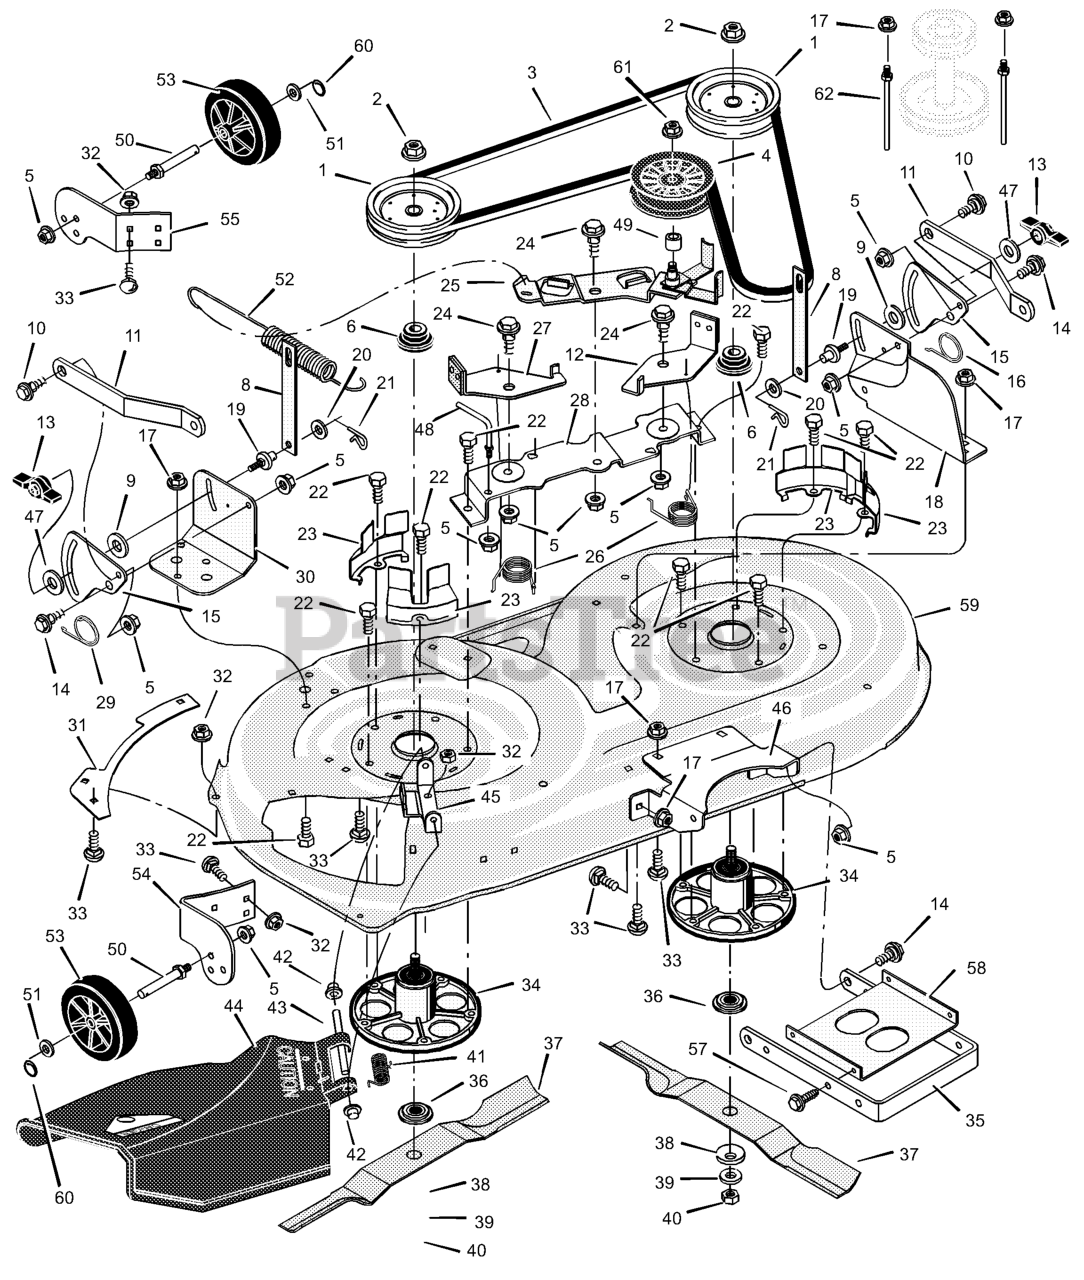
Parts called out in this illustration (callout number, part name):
1	Pulley, Jackshaft
2	Nut, Hex
3	Belt, Mower Drive
4	Pulley, Idler
5	Nut, Flange
6	Spacer, Pulley
8	Link, Lift
9	Pad, Friction
10	Bolt, Shoulder
11	Bracket, Suspension
12	Pad Assembly, Left Brake
13	Knob
14	Bolt, Shoulder
15	Plate, Suspension
17	Nut, Flange
18	Bracket, Suspension
19	Pin, Hanger
21	Pin, Hair
22	Bolt
23	Cover, Pulley
24	Bolt, Shoulder
25	Arm, Idler
27	Pad Assembly, Right Brake
28	Bracket, Brake
30	Bracket, Suspension
32	Nut, Flange
33	Bolt, Carriage
34	Mandrell Housing
35	Bracket, Suspension
36	Adapter, Blade
42	Cap, Push On
43	ROD, Deflector
44	Deflector Assembly
45	Bracket, Deflector Hinge
46	Bracket, Front Hanger
48	Guide, Belt
50	BOLT, Gauge Wheel
52	Spring, Extension
53	Wheel, Gage
54	Bracket, Right Wheel
55	Bracket, Left Wheel
58	Stiffener
59	Housing, Blade (Housing Only)
59	Housing, Blade, Complete (NO LONGER AVAILABLE)
60	Ring, Locking
61	Nut, Flange
62	Guide, Belt
